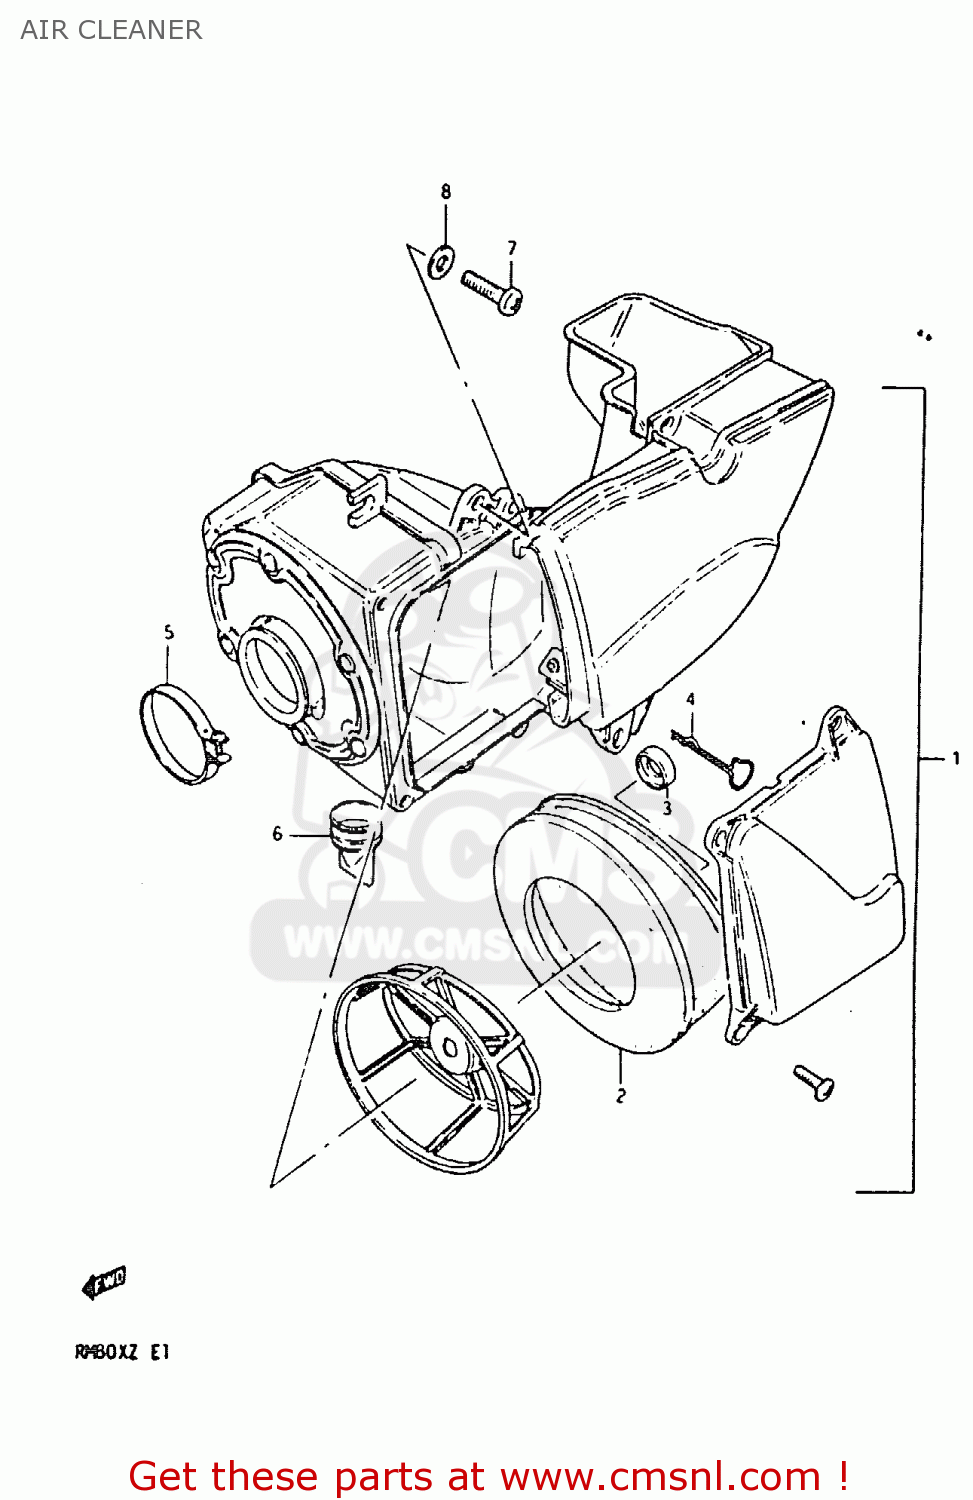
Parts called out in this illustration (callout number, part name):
1	CLEANER ASSEMBLY,AIR
2	FILTER,AIR CLEANER
3	WASHER
4	PIN,SNAP
5	CLAMP
6	HOSE,AIR CLEANER DRAIN
7	SCREW
8	WASHER
